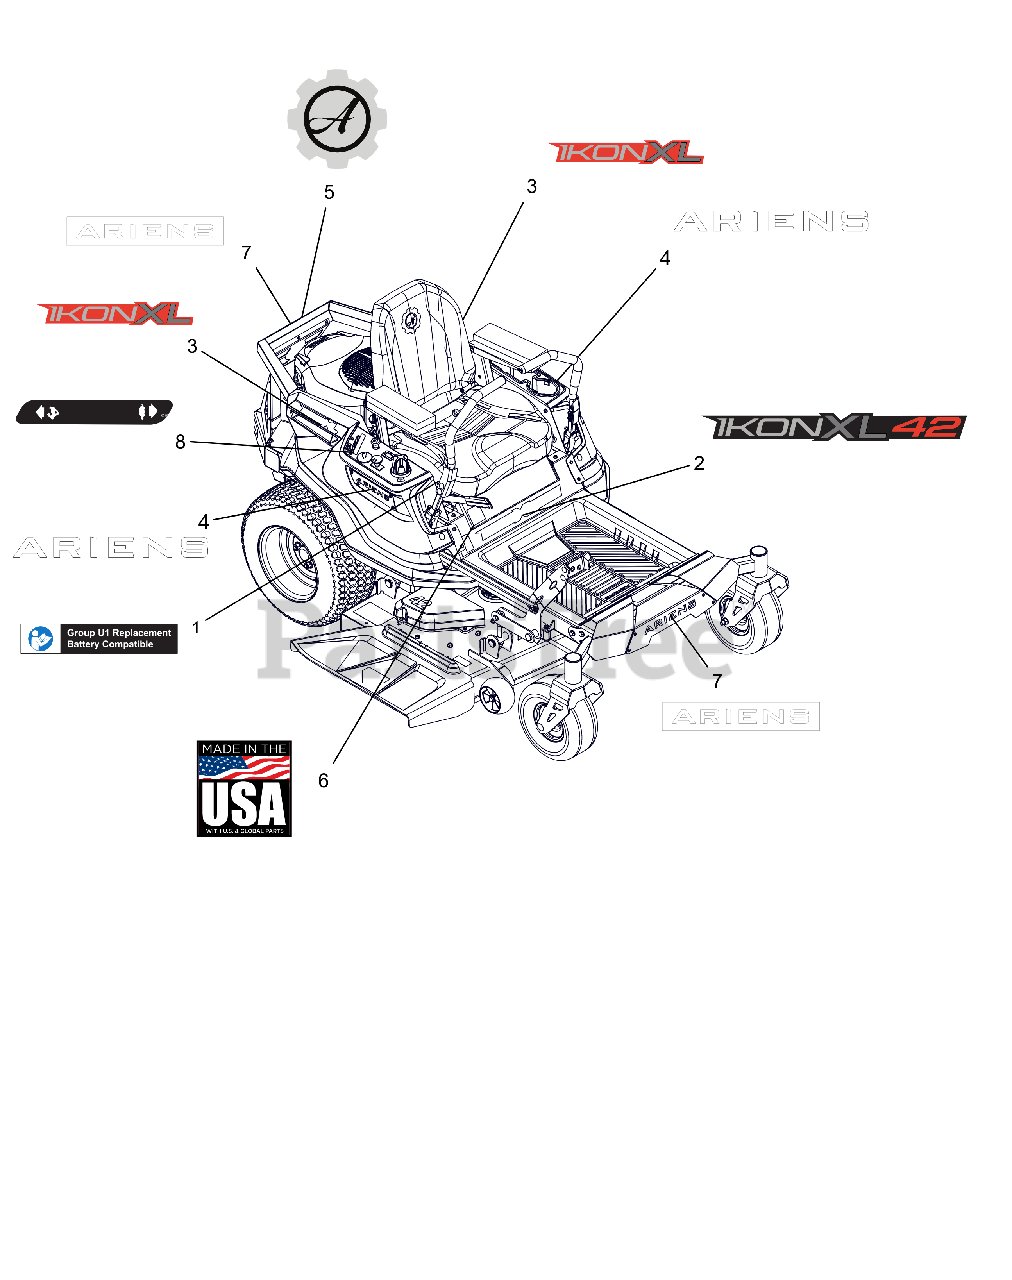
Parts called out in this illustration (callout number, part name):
1	DECAL, U1 BATTERY REPLACEMENT
2	DECAL, IKON-XL 42"
3	DECAL, IKON-XL
4	DECAL, ARIENS (6.50")
5	DECAL, ARIENS-GEAR BADGE
6	DECAL, MADE IN USA
7	DECAL - ARIENS 9.625"
8	DECAL, DASH DECAL
